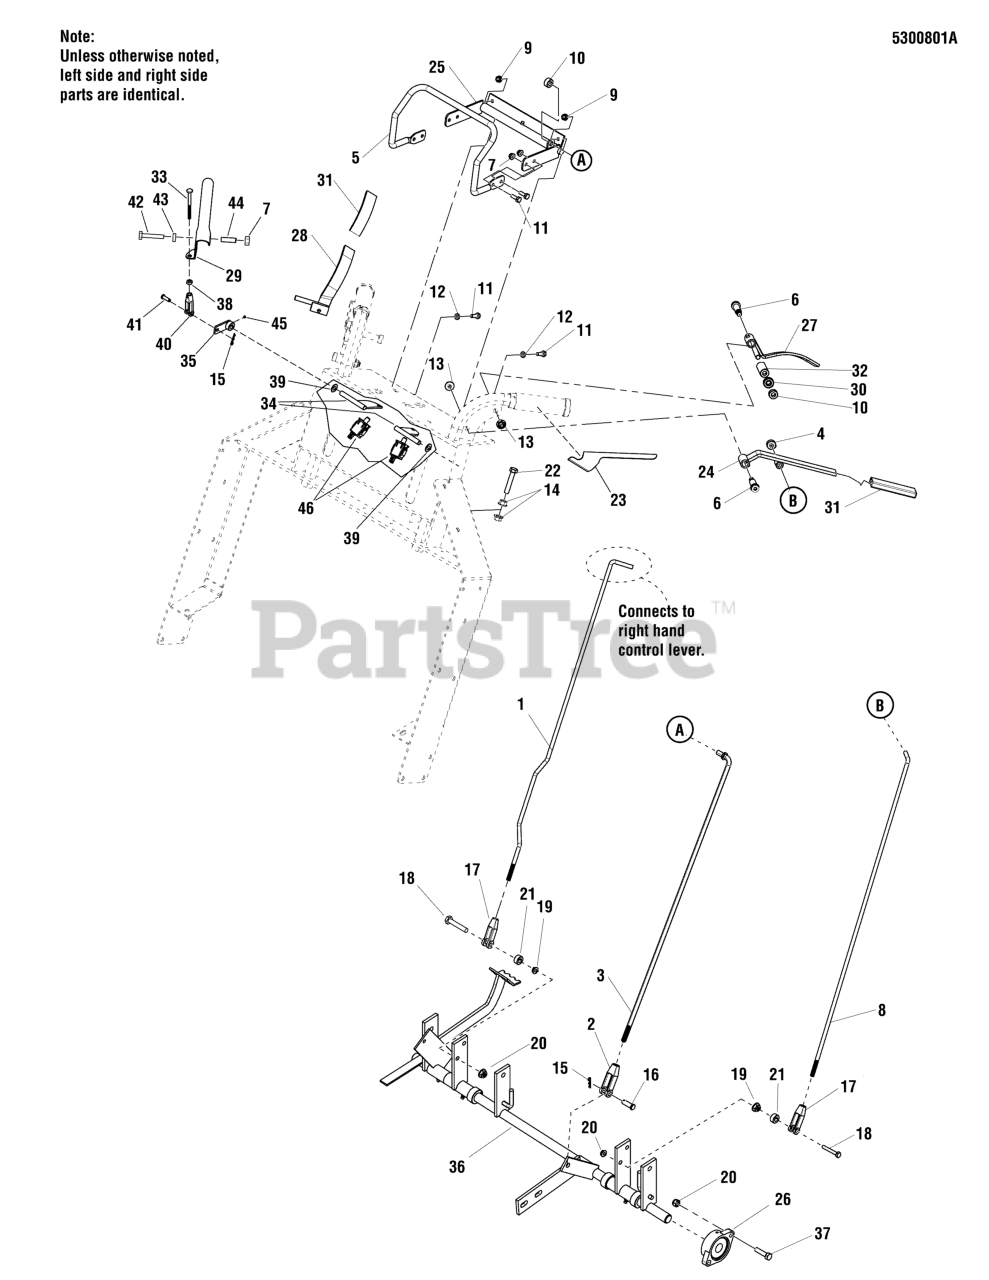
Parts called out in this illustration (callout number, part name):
2	CLEVIS, 3/8-24, PLASTIC
3	ROD, CRUISE CONTROL W/WASHER
4	SET COLLAR, 5/16"
5	BAR, SPEED CONTROL - DUAL DRIVE
6	SHOULDER BOLT, 1/2" X 1-1/2"
7	NUT, 1/4-20 HEX NYLOCK FLANGE
8	ROD, DDS REVERSE CONTROL - LH
9	NUT, 1/4-20 HEX SERR. FLANGE
10	COLLAR, 3/8" SET
11	BOLT, 1/4-20 X 3/4" GD5
12	WASHER, 1/4 SAE
13	NUT, 3/8-16 HEX NYLOCK FLANGE
14	NUT, 3/8-16 HEX LG. SERR FLG
15	PIN, HAIR, .0585 X 1-1/8
16	PIN, CLEVIS, 3/8" X 1-1/8"
17	CLEVIS, 5/16-24, STEEL, CLEAR ZINC
18	BOLT, 5/16-18 X 2
19	NUT, 5/16-18 HEX
20	NUT, 5/16-18 HEX NYLOCK FLANGE
21	SPACER, .33 X .50 X .25, CZ
22	BOLT, 3/8-16 X 1-3/4" TFL
24	WELD, HAND CONTROLS, DDS
25	WELD, SPEED CONTROL, DDS
26	BEARING, FLANGE
27	WELD, THUMB CONTROLS, DDS - LH
28	WELD, THUMB CONTROLS, DDS - RH
30	BEARING, R6-2RS
31	GRIP, FOAM, 1/4 X 1 X 4.1
32	SPACER, .38 X .50 X 1.25, CZ
33	ROD, OPC, LINK
34	ROD, OPC, FLAP
35	LINK, OPC, CCW
36	WELD, DDS CONTROL SHAFT
37	BOLT, 5/16-18 X 1" GD5 YZ
38	HN, 1/4F GR5 YZ
39	WASHER, 3/8 GR9 FLAT
41	PIN, CLEVIS, 1/4 X 7/8, PLATED
42	SPACER, .26 X .38 X 1.250 YZ
43	BOLT, 1/4 X 20 X 1-3/4 GD5 YZ
44	WASHER, 1/4 SAE
45	SET SCREW, 1/4-20 X 1/4"
46	SWITCH, PLUNGER, NC, SINGLE POLE, SNAP IN
